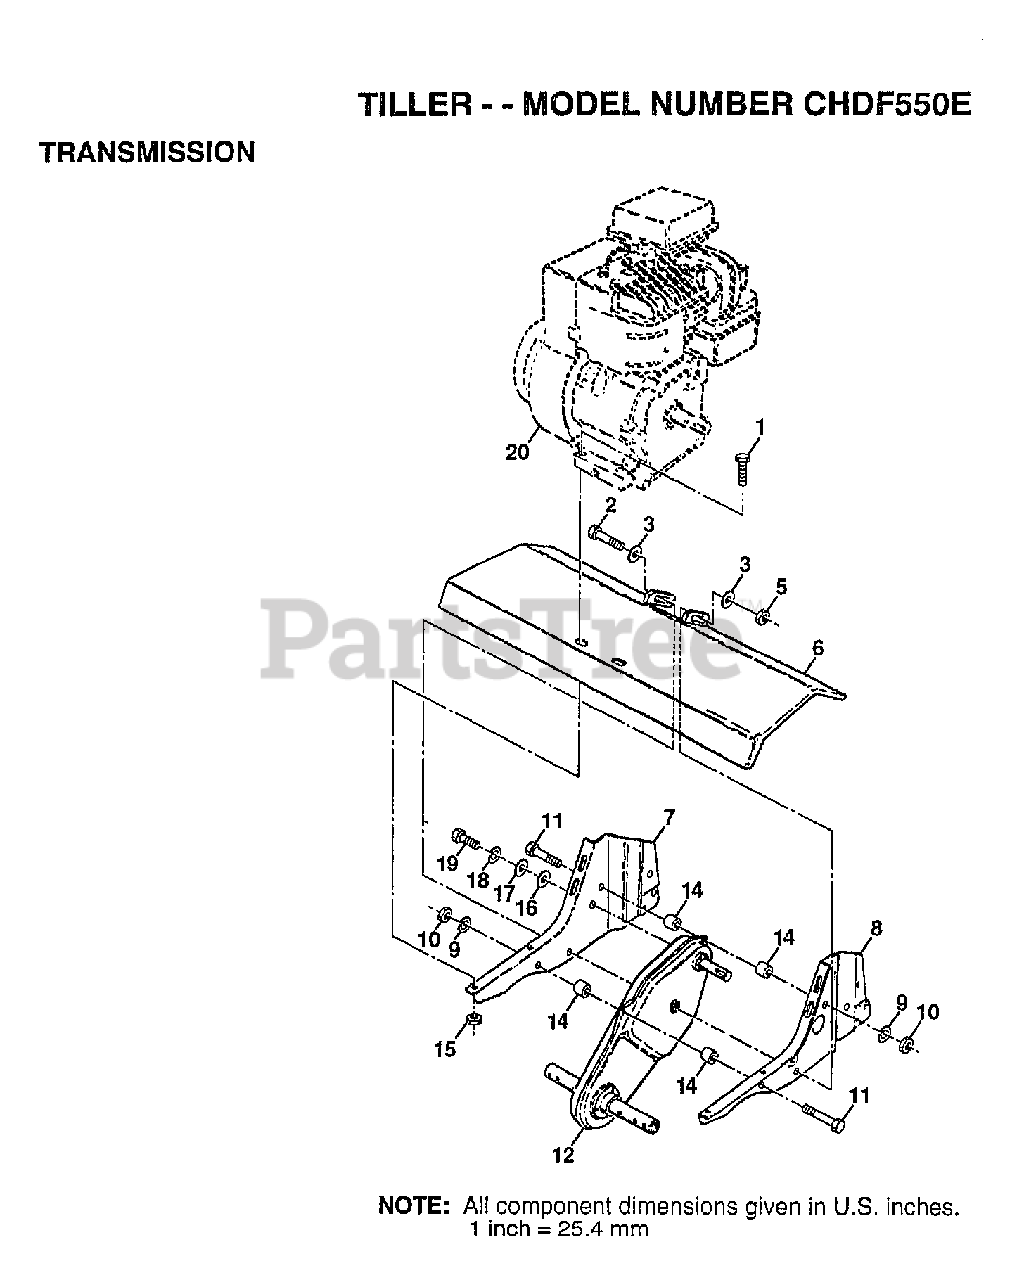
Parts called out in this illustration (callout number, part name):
1	BOLT.HEX.5/16-1.5
2	BOLT HEX 3/8-16
3	WASHER
5	NUT
6	SHIELD TINE
7	BRACKET.ENGINE.RH
8	ENGINE BRKT LH TI
9	LOCKWASHER
10	NUT.HEX.5/16-18
14	SPLIT SPACER RT
16	WASHER
17	WASHER
18	LOCKWASHER
19	BOLT
